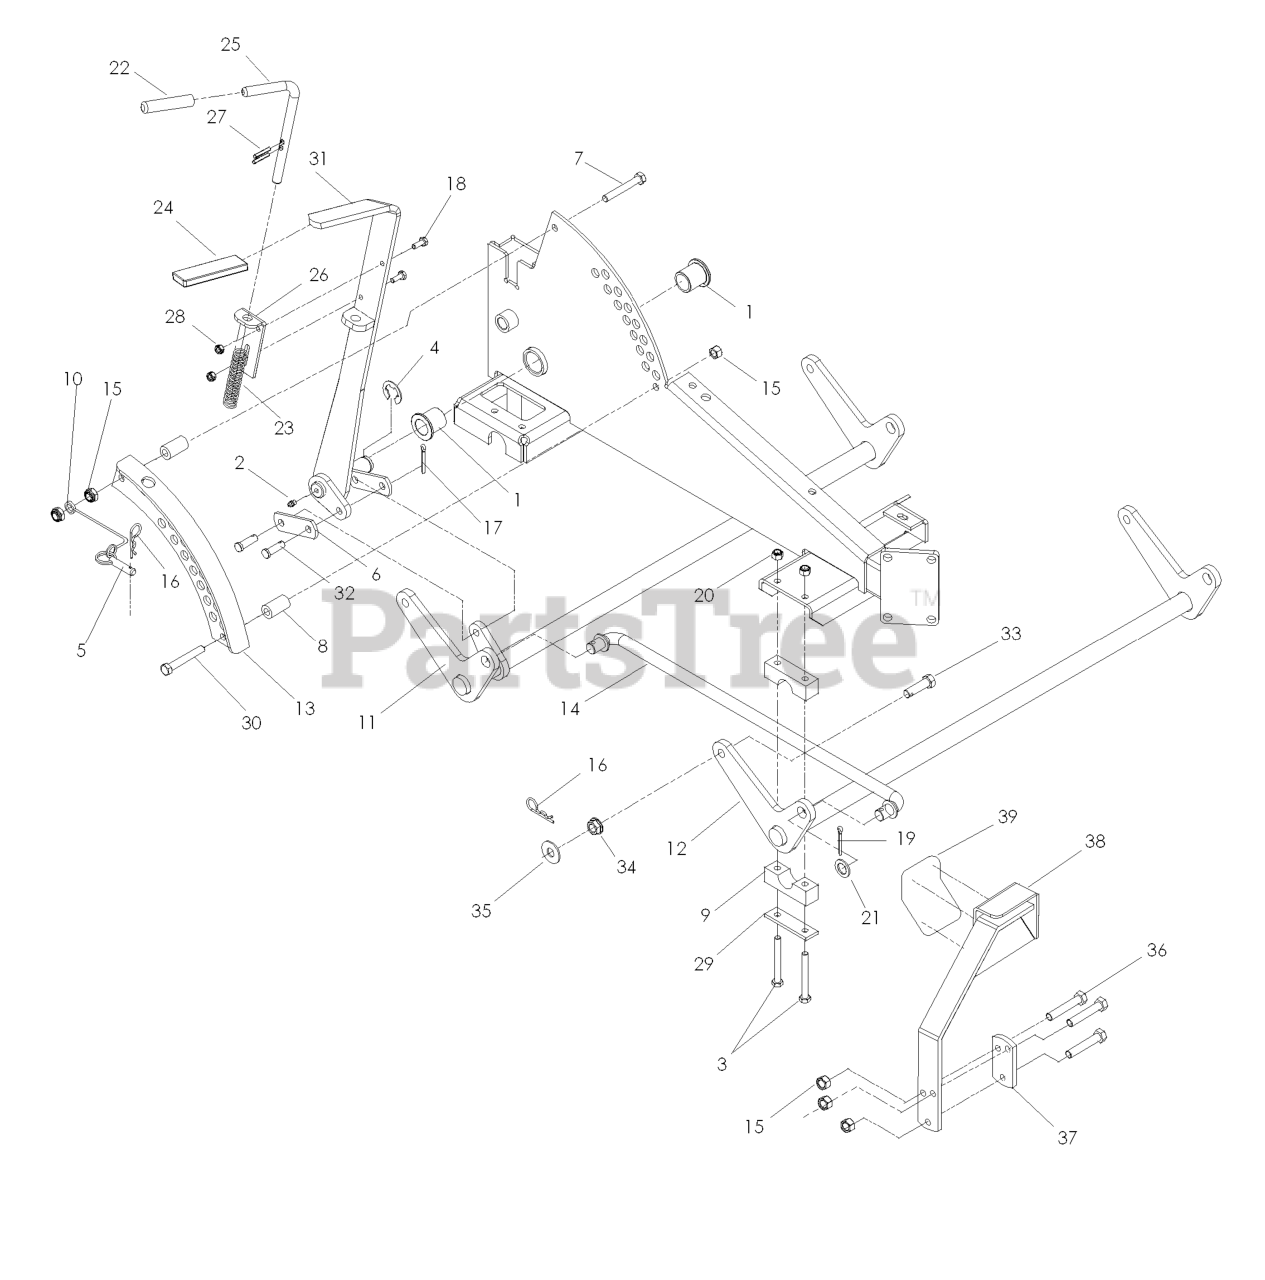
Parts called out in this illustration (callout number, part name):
1	BUSHING, FLANGED
2	ZERK
3	HCS 5/16C X 2-3/4
4	E-RING 7/8
7	SCREW 3/8C X 2 3/4 HEX CAP
8	DECK LIFT SPACER
9	PILLOW BLOCK
11	REAR LIFT SHAFT
12	FRONT LIFT SHAFT
13	ADJUSTMENT PLATE WLDMT
14	CROSS LINK
15	NUT 3/8-16 NYLOC
16	HAIRPIN #4
17	RP_COTTER PIN 1/8 X 3/4
18	HCS 1/4C X 3/4 HCS
19	COTTER PIN
20	NUT 5/16 NYLOC
21	BUSHING
26	PIN MT, UPPER
28	NUT 1/4C CENTER LOCK
29	REINFORCEMENT BAR
30	HCS 3/8C X 2 1/2
31	LIFT LEVER WELDMENT
32	CLEVIS PIN 3/8 X 1 1/8
33	HCS 7/16-14X1-1/2 GR5 ZD SPEC
34	NUT 7/16C WHIZ
35	WASHER 7/16 FLAT ZD
36	HCS 3/8C X 1 1/2
37	TIGHTENING PLATE BLK
38	LIFT PEDAL BLK
39	ANTI-SKID PAD
